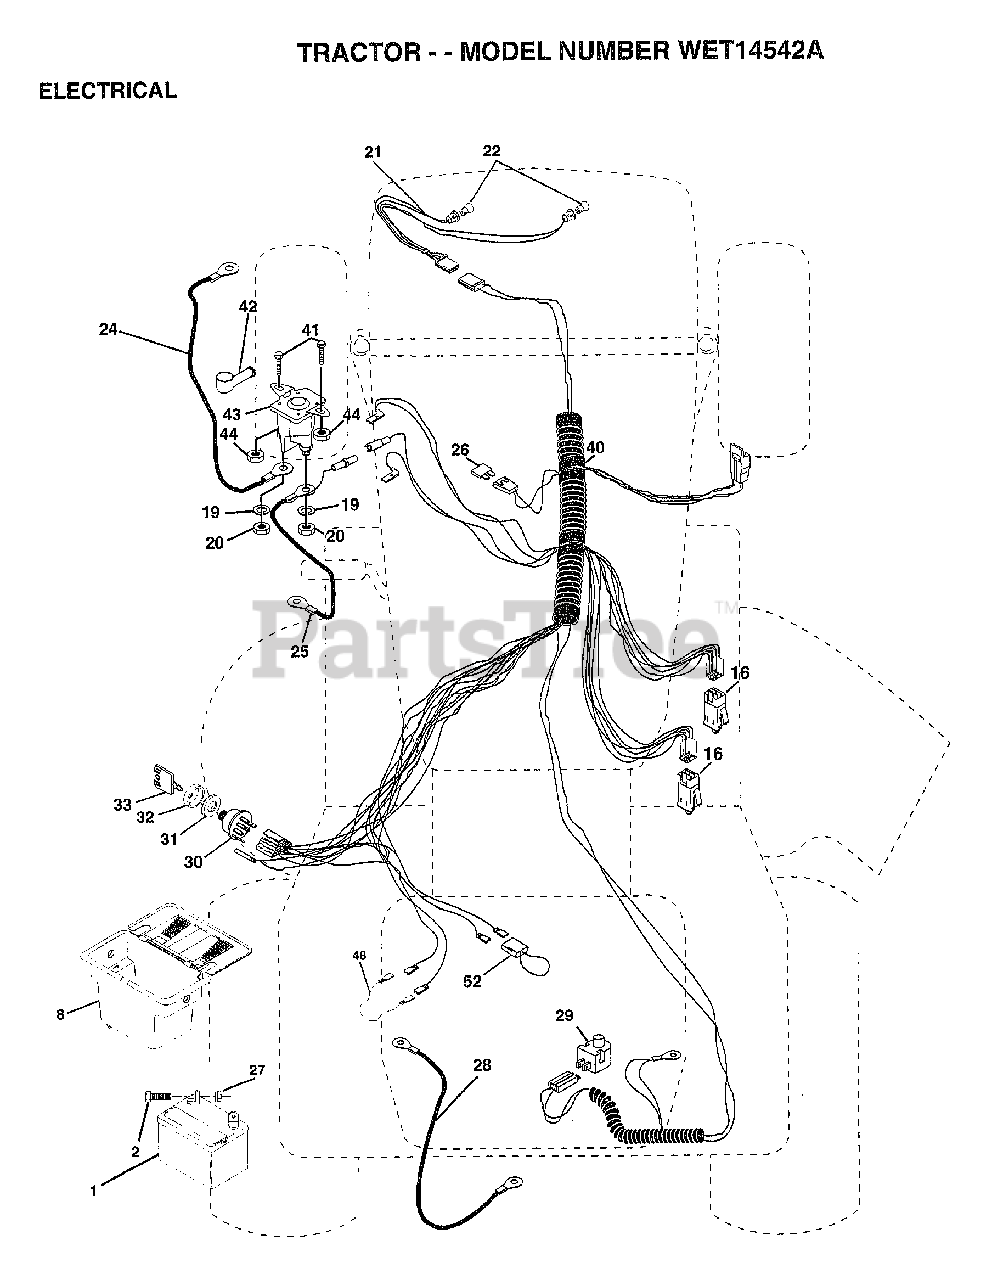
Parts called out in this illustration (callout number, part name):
2	BOLT LT
8	"CASE,BATTERY.MECH"
16	SWITCH INTERLOCK
20	NUT
21	HARNESS.ASM.LIGHT W/4152J
22	HEADLAMP BULB
24	CABLE ASM.
25	CABLE.BTRY.6GA.RD
26	FUSE.15 AMP
27	NUT
28	CABLE T
29	SWITCH SEAT
30	SWITCH IGN 4POS
31	NUT IGNITION
32	COVER KEY SWITCH
33	KEY
40	HARNESS.IGNITION
41	BOLT HXHD FIN
44	NUT HXKEP 1/4X20
48	ADAPTER AMMETER
52	PROTECTION LOOP
